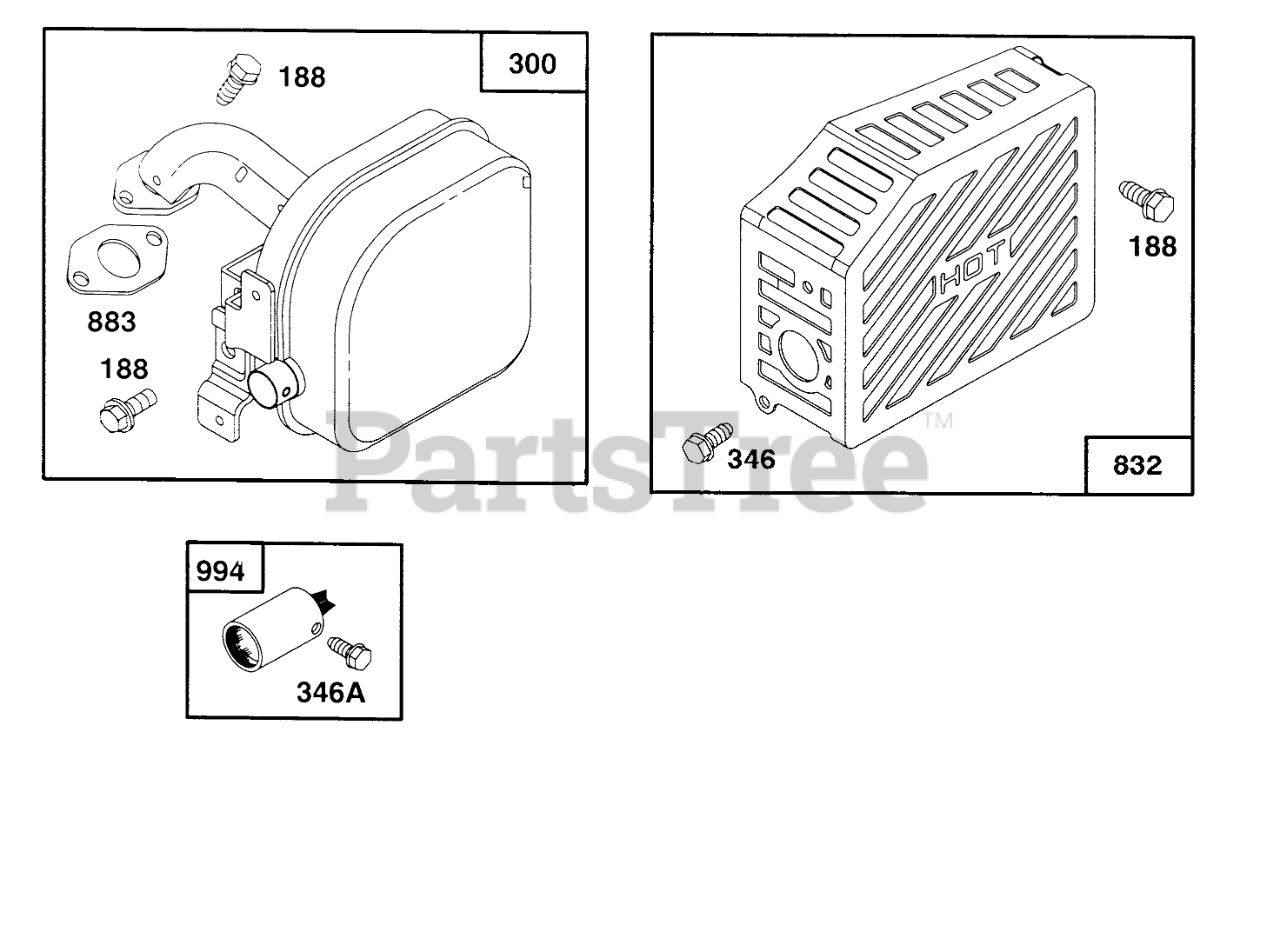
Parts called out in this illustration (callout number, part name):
188	SCREW - SEM
300	MUFFLER - EXHAUST
346	SCREW - SELF-TAPPING
346A	SCREW - ARRESTER MTG.
832	MUFFLER GUARD BLACK
883	EXHAUST GASKET
994	ARRESTER - SPARK
